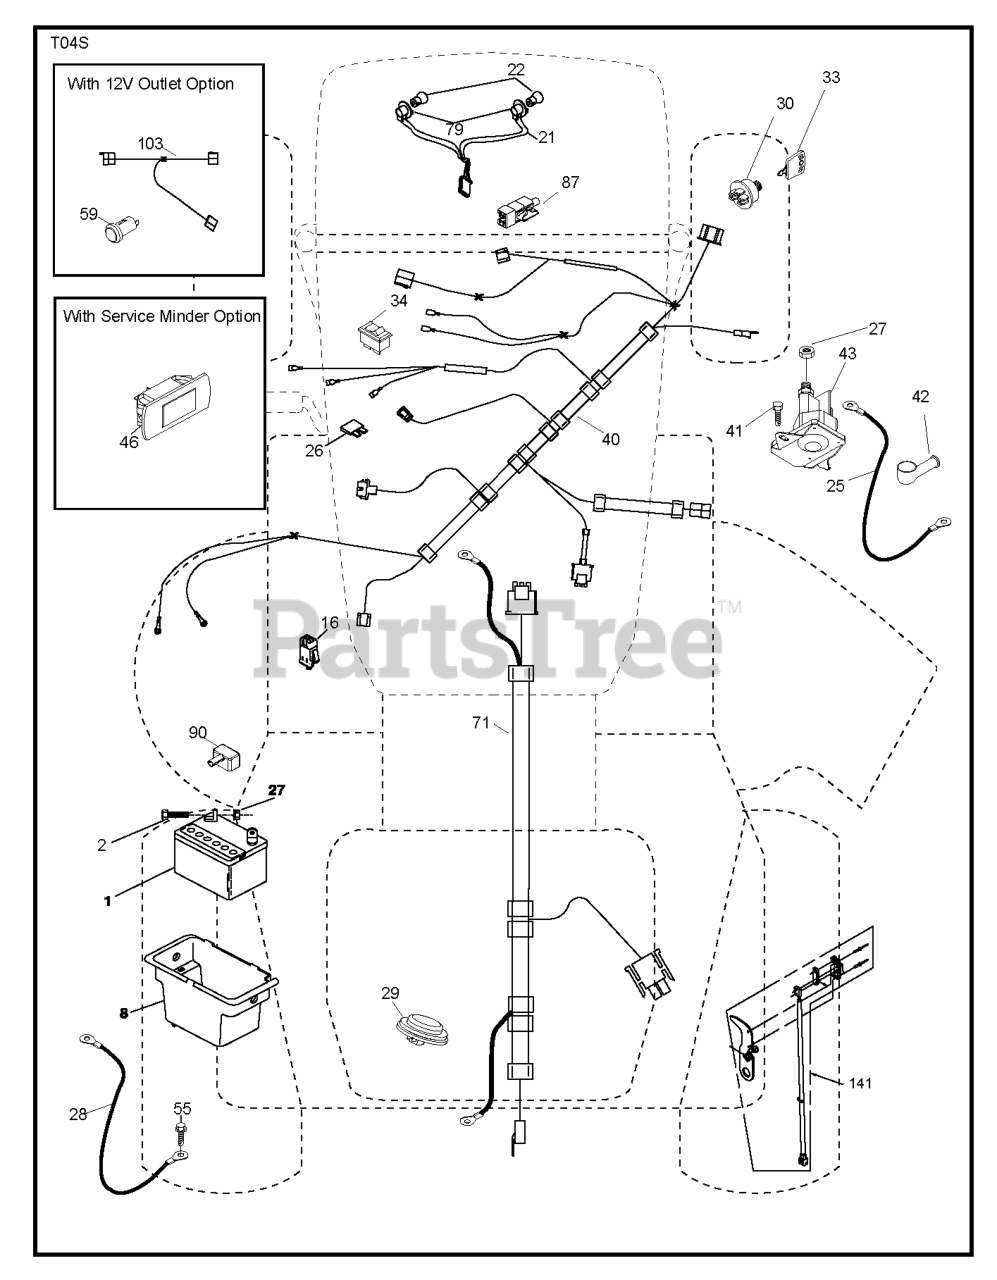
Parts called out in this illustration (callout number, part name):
1	REPL BY 532 12 38-99
2	BOLT.HEX.1/4.X.3/4.DICHROMATE
8	BOX.BATTERY.MNT.REAR.L
16	SWITCH INTERLOOK PUSH-IN
21	HARNESS.LIGHT W/4152J BULBS
25	CABLE.STARTER.6GA.BL/RED.14.
26	FUSE 20AMP
27	NUT
28	CABLE.BLACK.18"REAR.BA
29	SWITCH.SEAT.DELTA.OPC.
30	SWITCH.IGN.DELTA.W.LGH.ROS
33	KEY.CHAIN.BLISTER.PACK.GEN.USA
40	HARNESS IGN. DASH
41	SCREW
42	TERMINAL COVER
43	SOLENOID.W/BRASS.PLUNGER
46	RP.GUAGE.SRVCMNDR.HRMTR.
55	SCREW 5/16"
71	HARNESS.IGN.CHASS.TEX.REAR.BAT
79	BULB HOLDER ASM.
87	SWITCH.INTRLCK.CLUTCH.
90	COVER, TERMINAL BATTERY
141	KIT T2.ROS 71677
